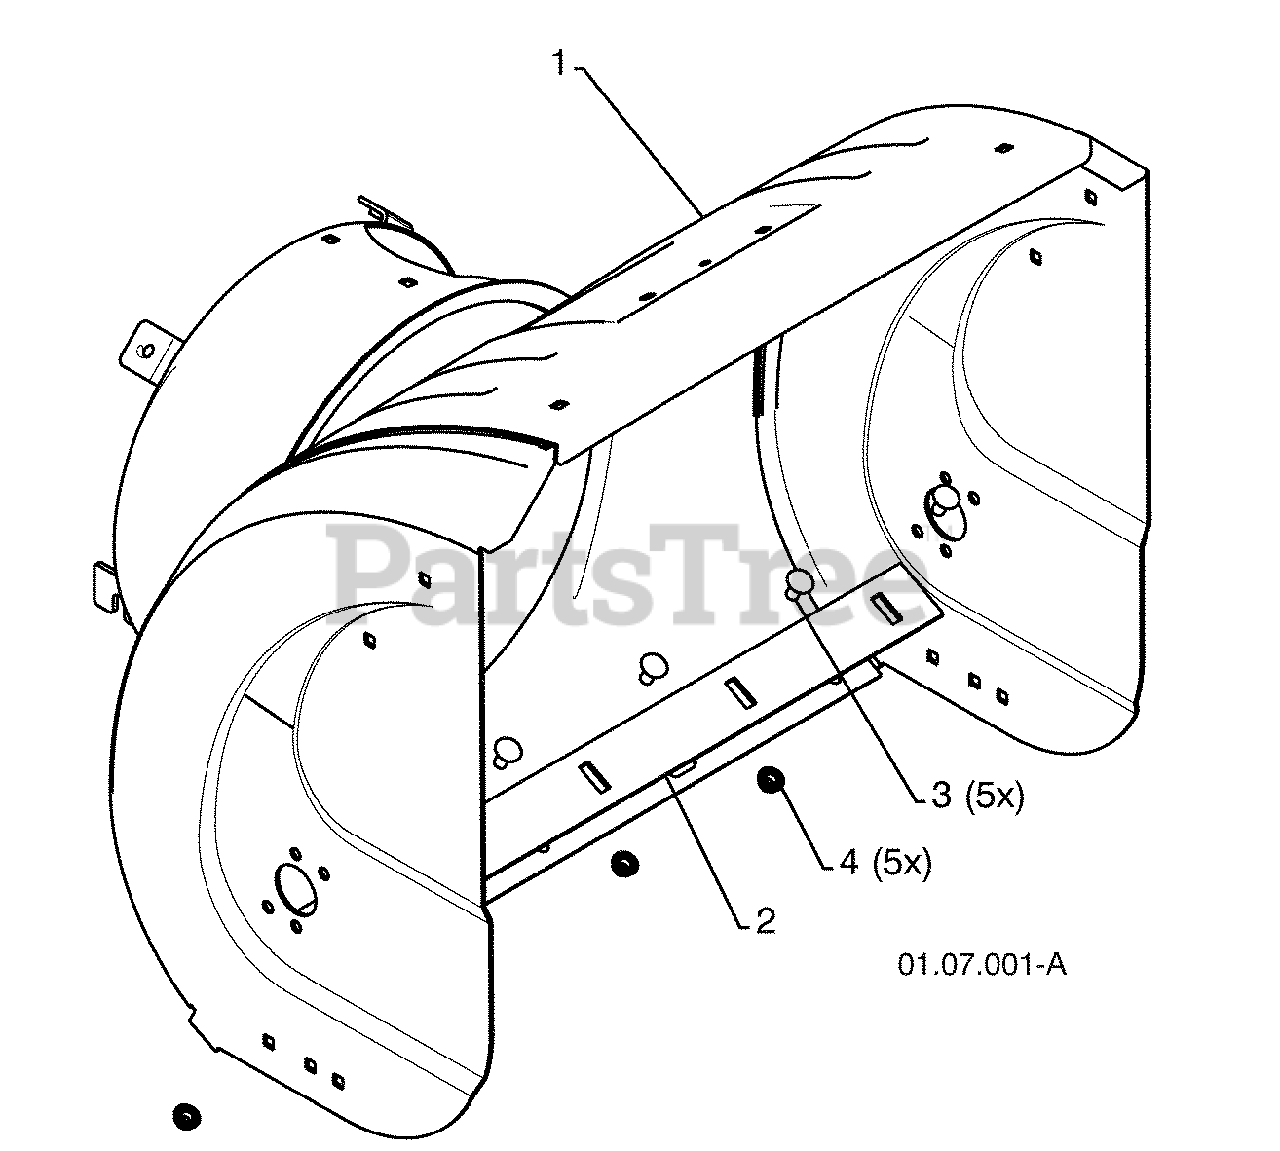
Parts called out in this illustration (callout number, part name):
1	AUGER HOUSING
2	SCRAPPER BAR
3	CARRIAGE BOLT 5/16--18 X .625
4	NUT 5/16--18
